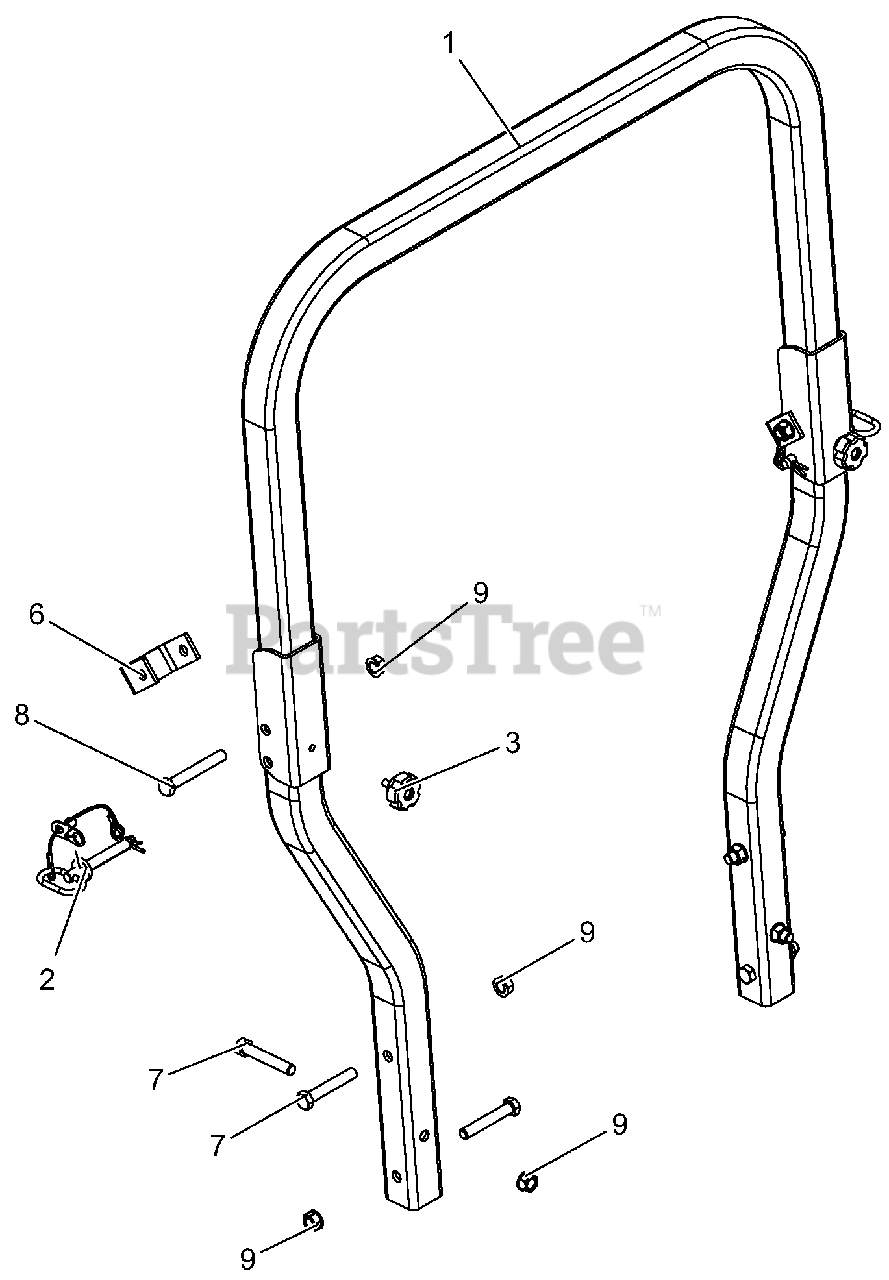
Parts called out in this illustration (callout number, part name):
1	ROPS INCLUDES HOOP RH AND LH SUPPORT
2	ASSY, ROPS PIN/LANYARD
3	KNOB, ROUND 5/16-18 X .750
6	BRKT, ROPS STOP
7	BLT-HEX .50-13X3.00 GR5 YWZC
8	BLT-HEX .50-13X3.50 GR5 YWZC
9	NUT, LK-TOP-FLG .50-13 YWZC
